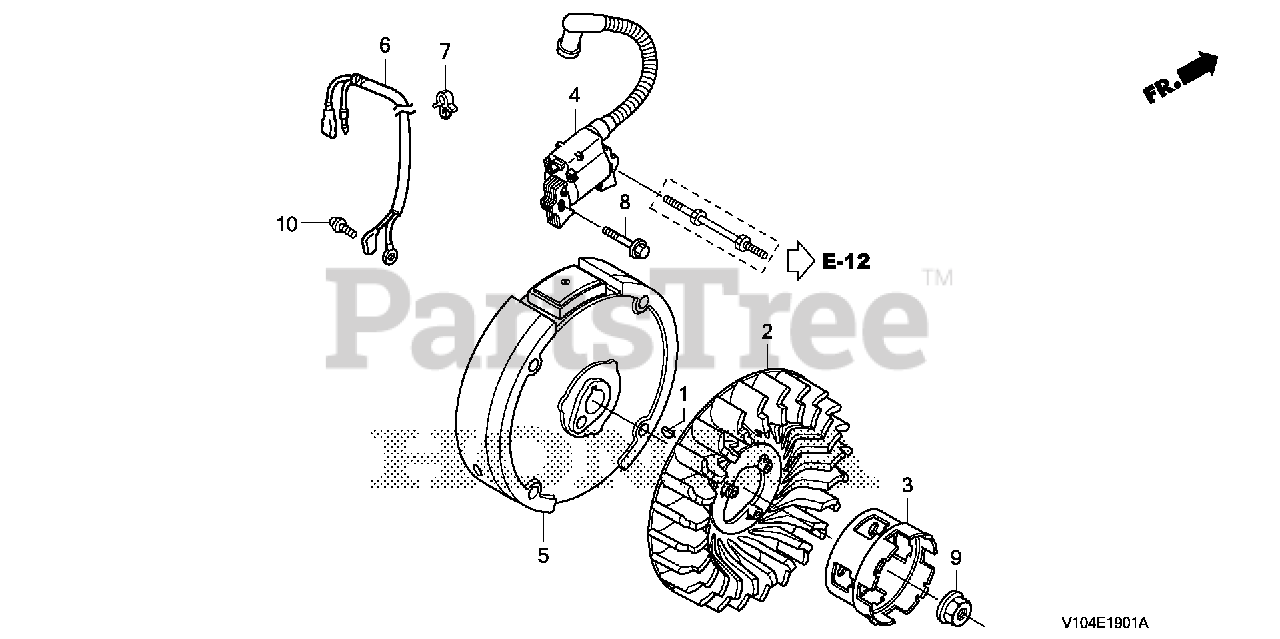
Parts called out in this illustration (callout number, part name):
1	KEY, SPECIAL WOODRUFF (25X18)
2	FAN, COOLING
3	PULLEY, STARTER
4	COIL ASSY., IGNITION (PHELON)
5	FLYWHEEL
6	WIRE, STOP SWITCH
7	CLIP, BRAKE PIPE (A)
8	BOLT, FLANGE (6X23) (CT200)
9	NUT, SPECIAL (14MM)
10	SCREW-WASHER (5X8)
